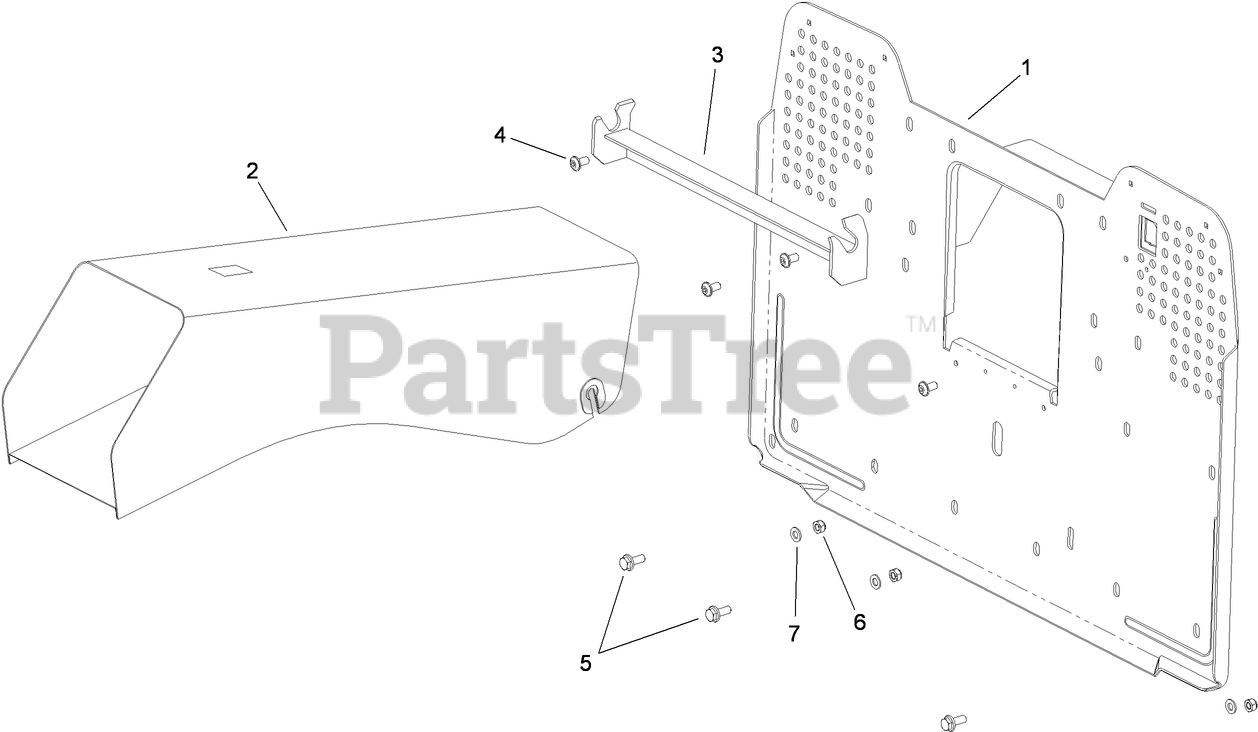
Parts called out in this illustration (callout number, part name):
1	COLLECTOR PLATE ASM
2	TUNNEL
3	SUPPORT-COLLECTOR
4	BOLT-CARRIAGE
6	NUT-LOCK, NI
7	WASHER-PLAIN
